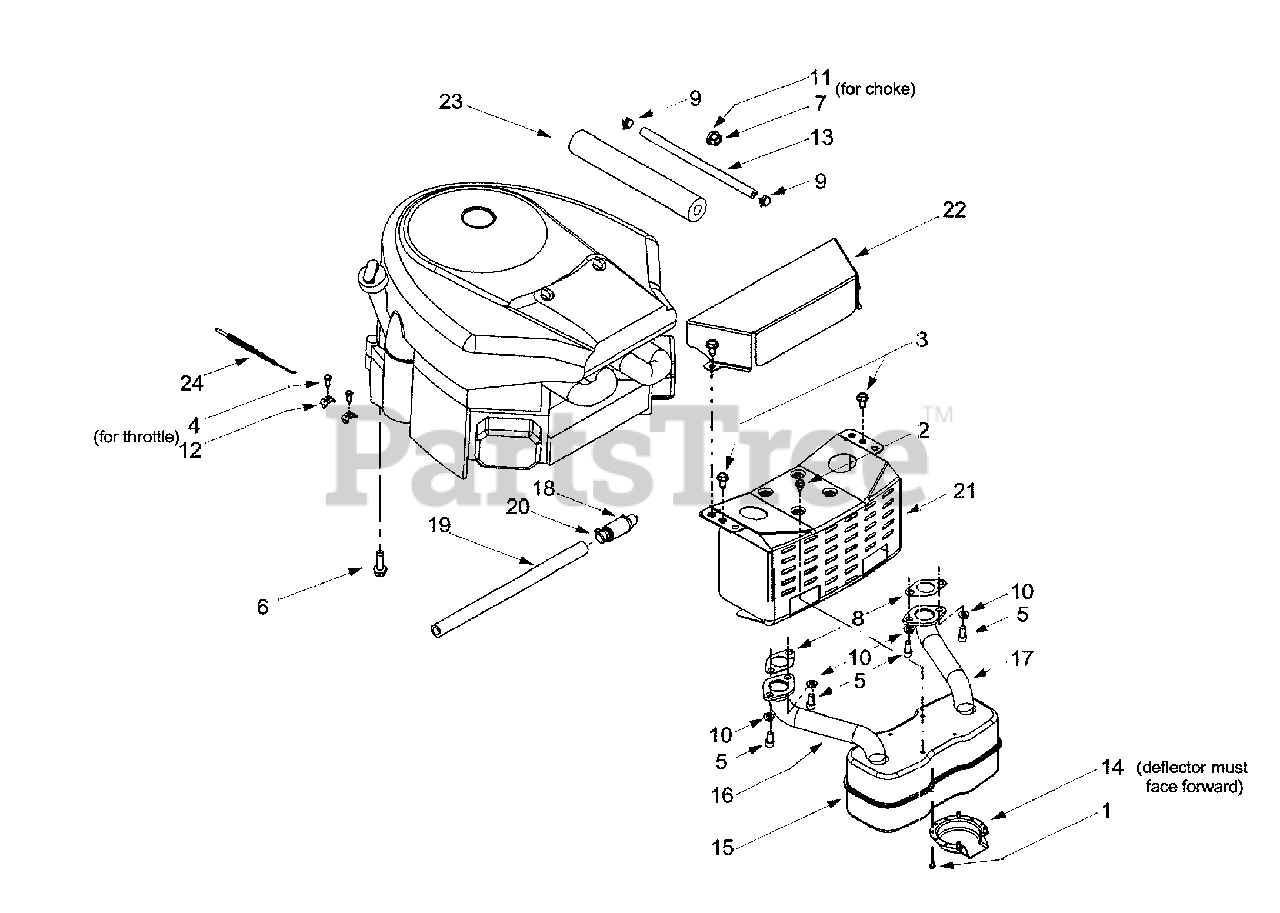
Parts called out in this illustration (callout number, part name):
1	Self-tapping Screw, #8-18 x .5
2	Self-tapping Screw, 1/4-20 x.5
3	Self-tapping Screw, 5/16-18 x .625
4	Screw, #10-32 x .625
5	Socket Cap Screw, 5/16-18 x .625
6	Self-tapping Screw, 3/8-16 x 1.25
7	Hex Nut, 3/8-16
8	Exhaust Gasket
9	Hose Clamp
10	Lock Washer, 5/16
11	Flat Washer, .406 x .875 x .059
12	Casing Clamp
13	Fuel Line Hose
14	Muffler Deflector
15	Muffler, Twin Inlet
16	RH Exhaust Pipe
17	LH Exhaust Pipe
18	Oil Drain Valve
19	Oil Drain Hose
20	Oil Drain Cap
22	Engine Heat Shield
23	Foam
24	Throttle Cable
